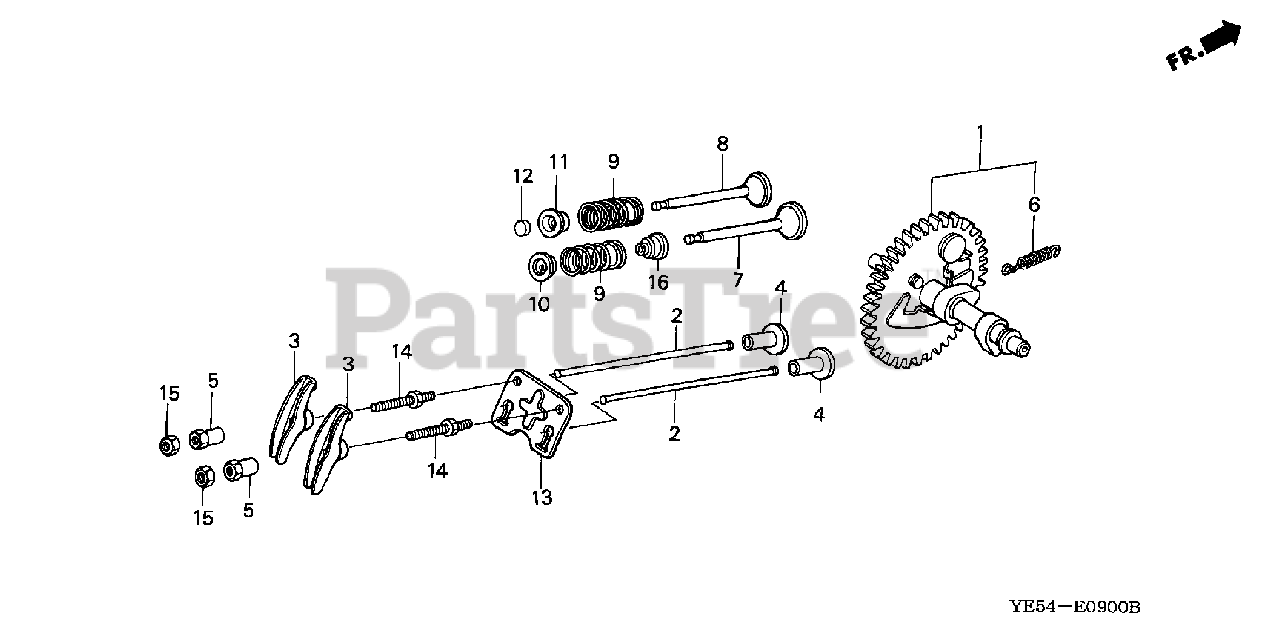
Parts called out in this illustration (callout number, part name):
1	CAMSHAFT ASSY.
2	ROD, PUSH
3	ARM, VALVE ROCKER
4	LIFTER, VALVE
5	PIVOT, ROCKER ARM
6	SPRING, WEIGHT RETURN
7	VALVE, IN.
8	VALVE, EX.
9	SPRING, VALVE
10	RETAINER, IN. VALVE SPRING
11	RETAINER, EX. VALVE SPRING
12	ROTATOR, VALVE
13	PLATE, PUSH ROD GUIDE
14	BOLT, PIVOT (8MM)
15	NUT, PIVOT ADJ.
16	SEAL, VALVE STEM
